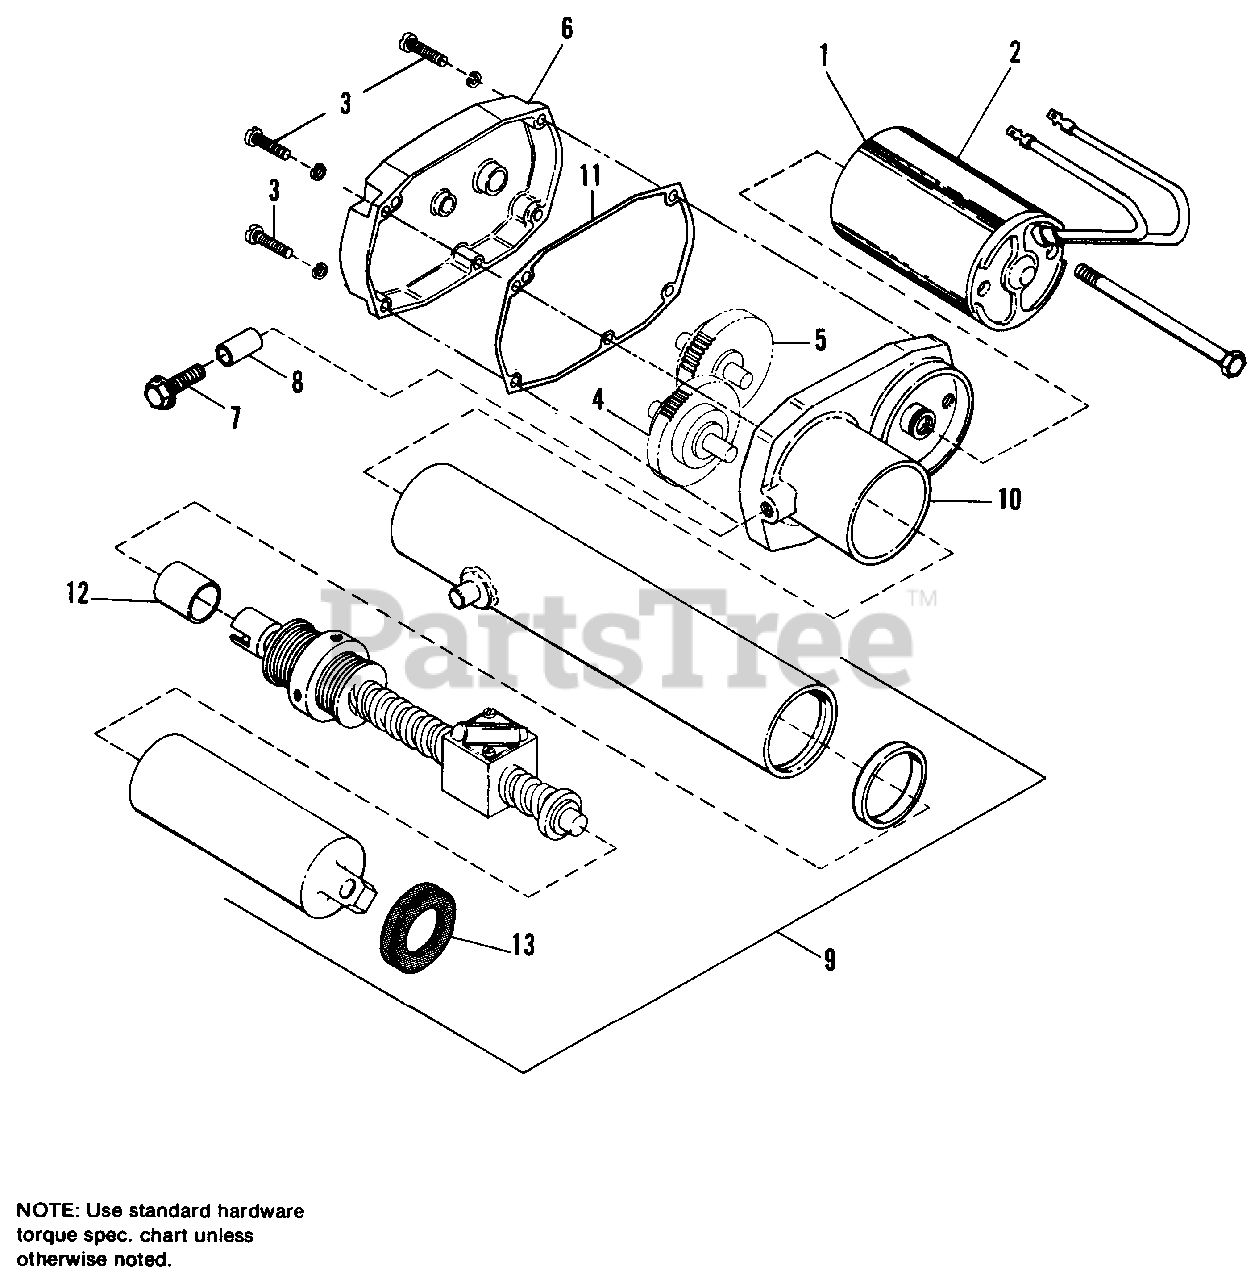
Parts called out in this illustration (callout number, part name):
1	BRUSH, w/Spring Set (Motor)
2	12 VOLT DC MOTOR
3	SCREW, Fillister Hd.
4	GEAR ASSY., 4th
5	GEAR ASSY., 2nd & 3rd
6	COVER, Housing
7	CAPSCREW, Thd. Forming
9	BALL SCREW ASY.
10	HOUSING, Motor
11	GASKET, Cover
13	SEAL, Rubber
